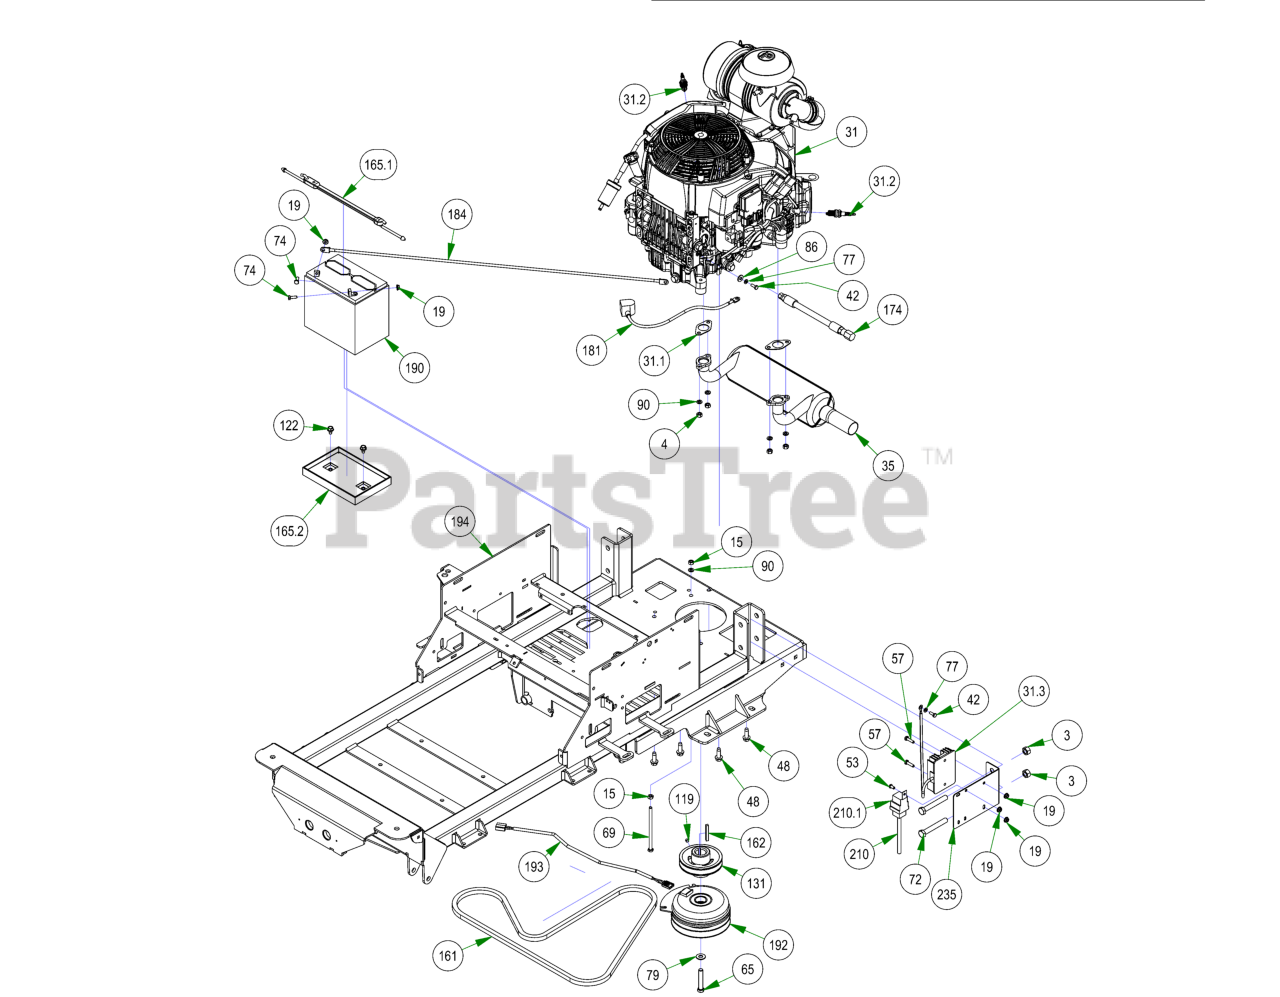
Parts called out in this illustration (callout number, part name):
3	1/2-13 HEX 2-WAY REVERSIBLE CENTER LOCKNUT Grade B ZINC
4	M8-1.25 DIN 934 HEX NUT (CL.8) ZINC
15	5/16-18 HEX NUT ZINC
19	1/4-20 HEX SERRATED FLANGE NUT HARD/ZINC
31	Honda GXV700 1 1/8"dia x 3.8"Length Crank Shaft
31.1	Exhaust Gasket
31.2	Spark Plug
31.3	Regulator Rectifier for Honda Engine
35	2019 Honda Maverick Muffler
42	M6-1.0 X 16MM DIN 933 HEX TAP BOLT (CL 8.8) ZINC
48	3/8-16 X 1-1/8 HEX WASHER UNSLOT SERRATED (TRI-LOB) TRS ZINC YELLOW
53	1/4-20 X 1/2 BUTTON SOCKET CAP SCREW 18-8 STAINLESS STEEL
57	1/4-20 X 1 HEX CAP SCREW (GR.5) ZINC
65	7/16-20 X 2-1/2 HEX Bolt GR 8 W/ Patch
69	5/16-18 X 5-1/2 HEX CAP SCREW (GR.5) ZINC
72	1/2-13 X 3-1/2 HEX CAP SCREW (GR.5) ZINC
74	1/4-20 X 3/4 HEX CAP SCREW (GR.5) ZINC
77	1/4 SPLIT LOCKWASHER ZINC
79	3/8 FLAT WASHER USS (1" OD) ZINC
86	1/4 USS FLAT WASHER (3/4 OD) ZINC
90	5/16 SPLIT LOCKWASHER ZINC
119	5/16-24 X 1/4 SOCKET SET SCREW (CUP PT) PLAIN
122	5/16-18 X 1/2 HWH unslot (F) tcs zinc
131	4 3/4 Motor Pulley
161	75.8" Pump Belt
162	1/4 X 2 SQ MACHINERY KEY 1018 STL PLAIN
165	2023 Battery Hold Down Assembly Strap
165.1	2023 Rubber Battery Hold Down Strap
165.2	Battery Tray
174	2019 Honda Oil Drain
181	24 inch Black Cable – MZ/ZT
184	36" Red Battery Cable
190	SP-35 Battery
192	Clutch Assembly
193	Clutch Pigtail
194	2023 Maverick Frame - Painted
210	Honda Maverick HD Pigtail
210.1	2022 Relay for the 086-9019-00
235	Honda Rectifier Mount
